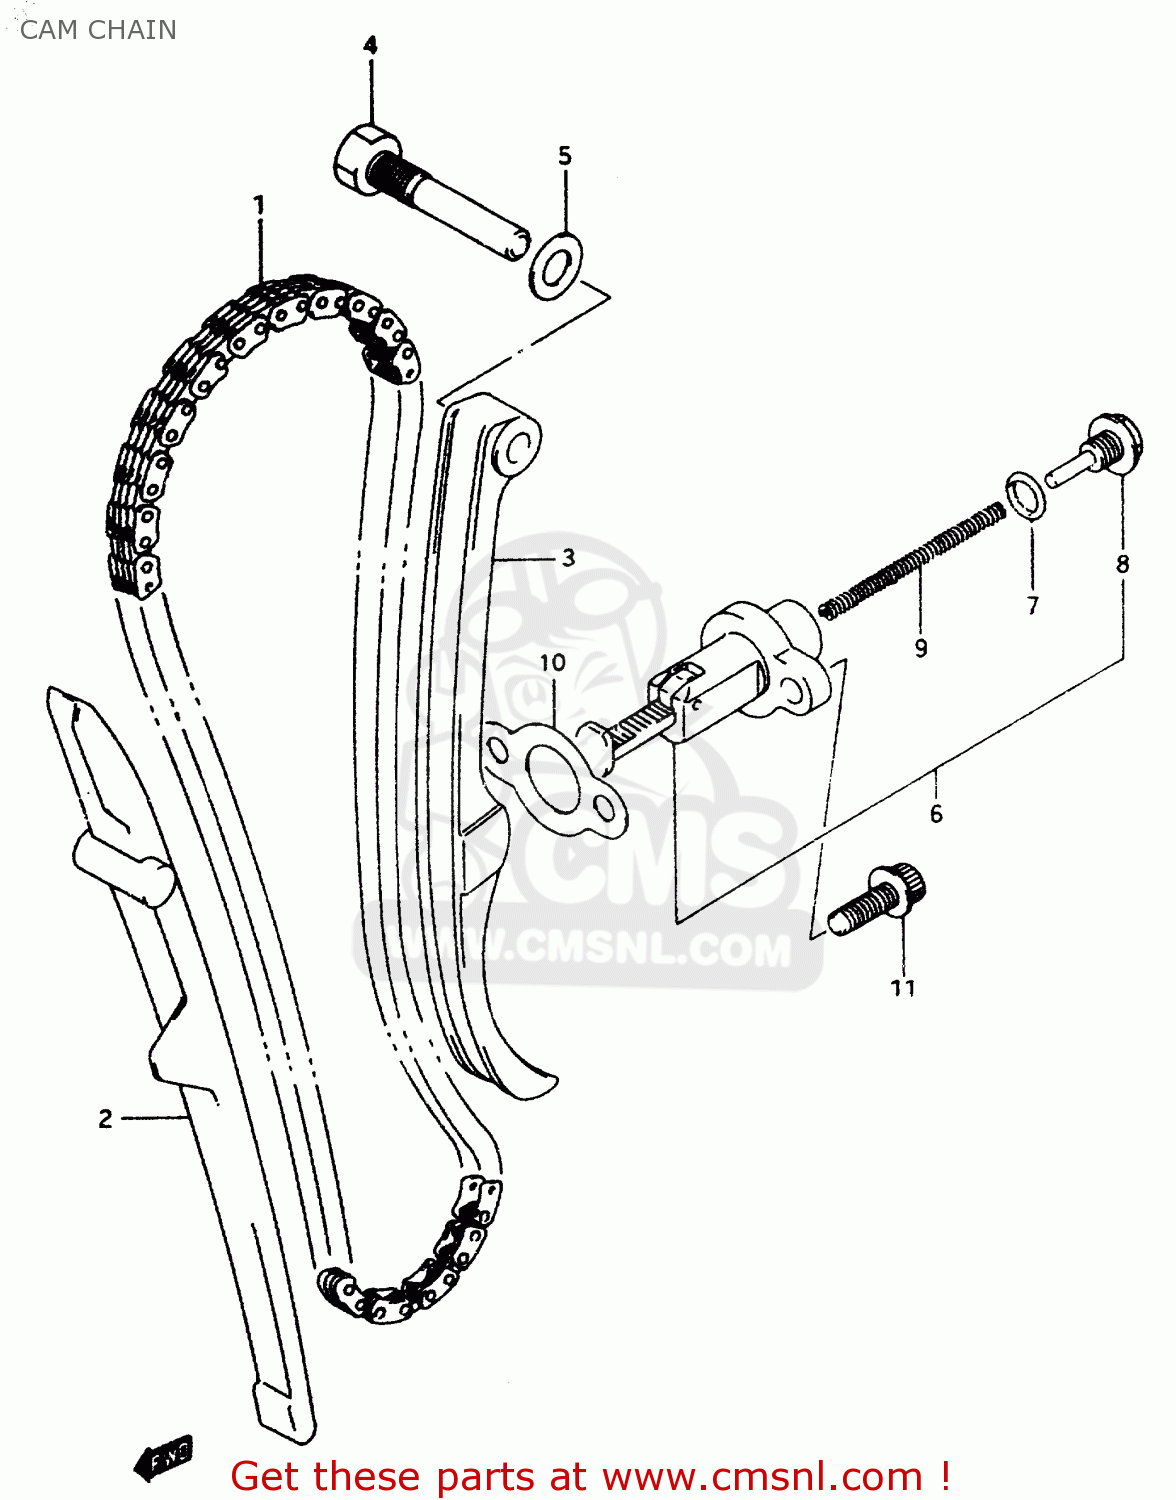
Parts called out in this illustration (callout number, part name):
1	CHAIN,CAMSHAFT DRIVE
2	GUIDE,CAM CHAIN
3	TENSIONER,CAM CHAIN
4	BOLT,CAM CHAIN TENSIONER
5	GASKET 8.2X14X1 (NAS)
6	ADJUSTER ASSY,TENSIONER
7	O RING
8	PLUG,ADJUSTER
9	SPRING
10	GASKET,TENSIONER ADJUSTER (NAS)
11	BOLT
